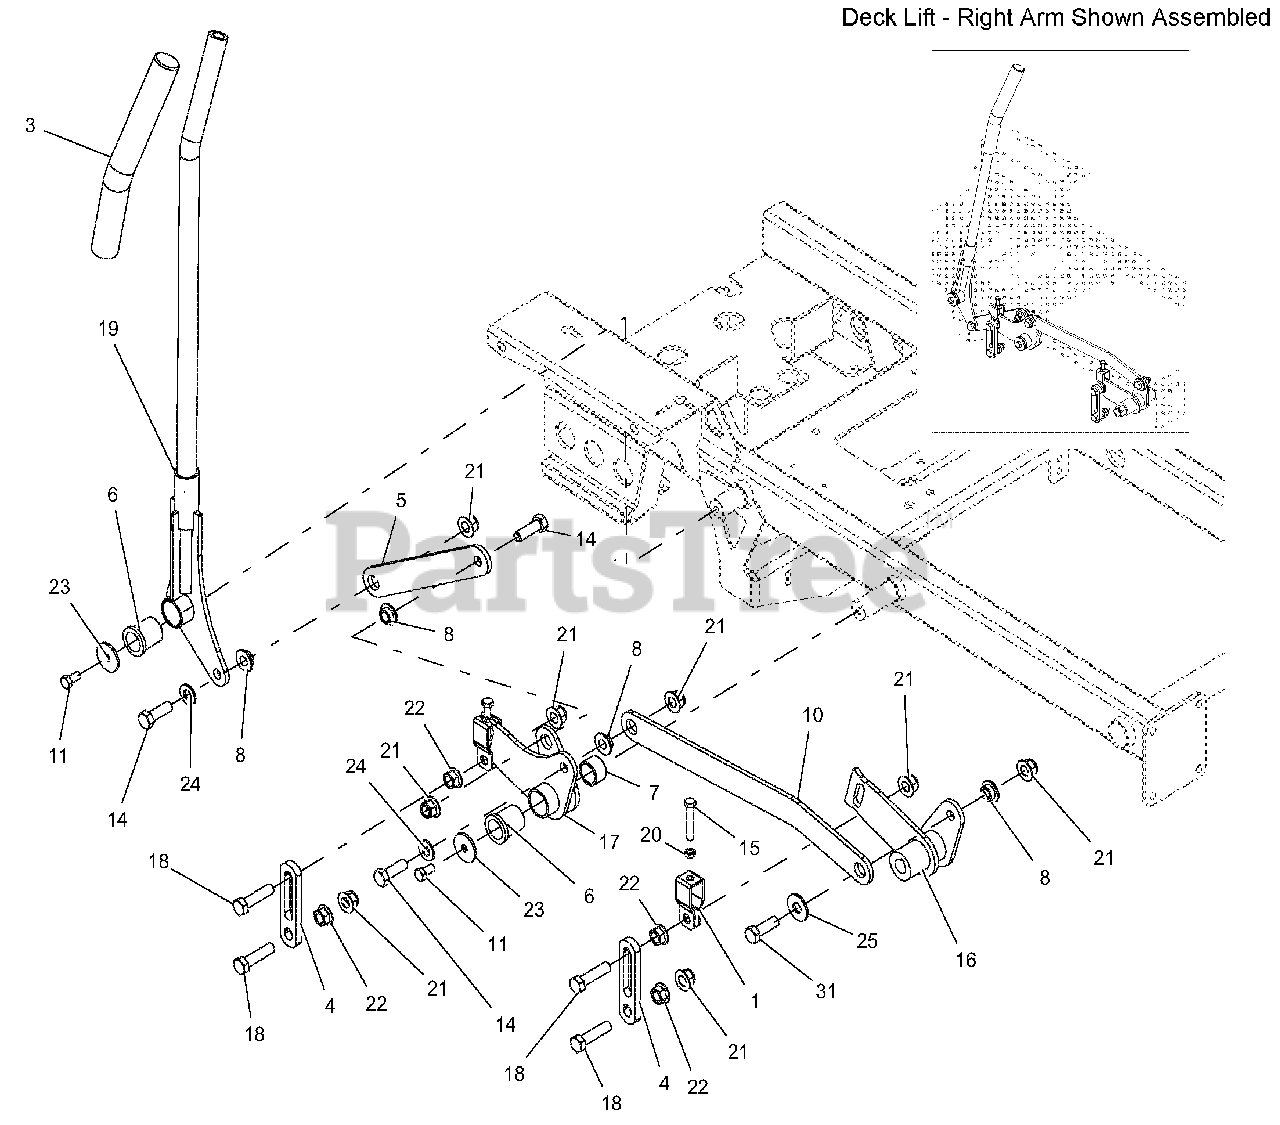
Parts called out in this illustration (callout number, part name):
1	BRKT, DECK LEVELING
3	GRIP, HANDLEBAR
4	LINK, DECK LIFT - SHORT
5	LINK, DECK LIFT HANDLE
6	BSHG-FLG 1.00X1.25X1.5X1. 5
7	BSHG, 1.00 X 1.25 X .75
8	BSHG, FLANGE .515X.750X.420X1.12
10	PLATE, DECK ARM
11	BLT-HEX .38-16X.75 GR5 YWZC
14	BLT-HEX .50-13X1.50 GR5 YWZC
15	BLT-HEX .31-18X2.00 FTH GR5 YWZC
16	WLDMT, RH FRONT DECK ARM (BLACK)
17	WLDMT, REAR DECK ARM
18	BLT-HEX .50-13X2.00 GR5 YWZC
19	WLDMT, DECK LIFT HANDLE
20	NUT, JAM .312-18 YWZC
21	NUT-LK-NYL-FLG .50-13 YWZC
22	NUT .50-13 WIZ FLANGE
23	WSHR-FL-STL .380X1.50X.125 YWZC
24	WSHR-FL-STL.531X1.06X.095YWZC
25	WSHR-FL-STL.563X1.38X.109YWZC
31	BLT-HEX .50-13X1.50 GR5 YWZC
